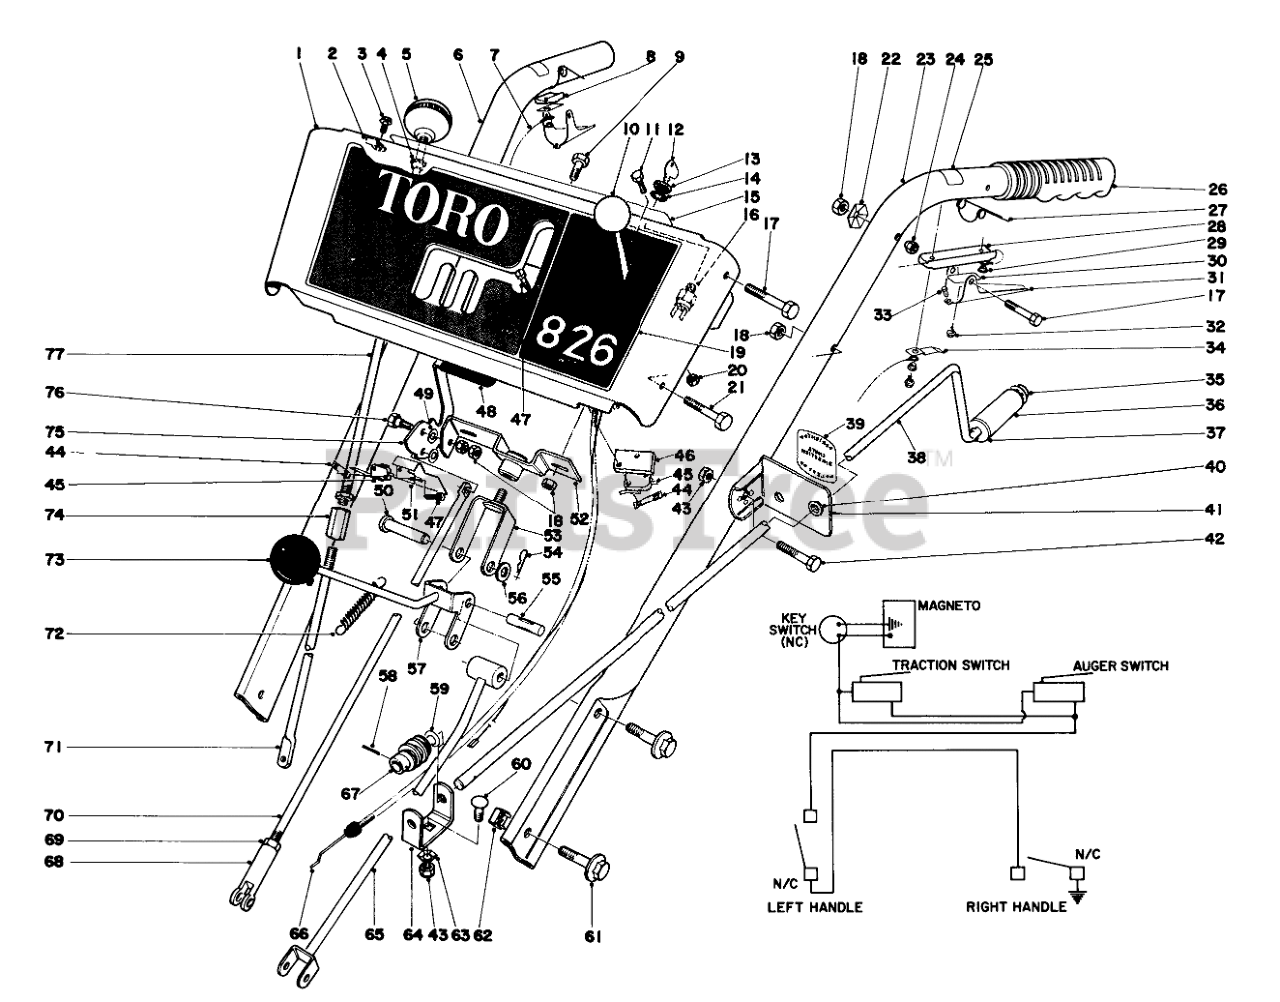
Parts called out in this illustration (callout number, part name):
1	Escutcheon Plate (Incl. Ref. #15 & 19) (Model 31763)
2	PLASTIC CLIP
3	SCREW-HWHTF
4	Nyliner Bushing
5	KNOB-LEVER
6	Handle Right
7	Wire Harness
8	Insulator
9	SCREW-HH
10	KNOB-CONTROL
11	HEX HEAD SEMS 10-24X1/2
12	Ket (set of 2)
13	NUT-HH
14	WASHER-TOOTH, INTERNAL
15	Decal Escutcheon Back
16	Switch
17	SCREW-HH
18	NUT-LOCK, CONE
19	Decal Escutcheon (Model 31763)
20	Nut
21	SCREW-HH
22	Washer
23	Handle L.H.
24	NUT-CAP
25	Decal Safety Interlock
26	Grip Handle
27	INTERLOCK SPRING
28	Insulator
29	WASHER INSULATOR
30	INTERLOCK CONTACT
31	Safety Lever
32	Screw
33	1/4 PLASTIC RIVET
34	CONTACT BRACKET
35	RETAINER-PUSH ON
36	CHUTE CONTROL GRIP
37	WASHER-FLAT
38	ROD CHUTE CONTROL
39	Decal Chute Direction
40	Bushing
41	Bracket Chute Control Mounting (Incl. Ref. #39 & 40)
42	SCREW-HH
43	NUT-LOCK, CONE
44	NUT-SPEED
45	MICRO SWITCH
46	SWITCH MTG PAD
47	SCREW-SPH
48	AUGER CLUTCH HND GRIP
49	WASHER-PLAIN
50	PIN-CLEVIS
51	SWITCH BRKT
52	SWIVEL BLOCK WA
53	Pivot Bracket
54	PIN-HAIR
55	3/8 X 1-1/4 ROL
56	WASHER-FLAT
57	Rod Shift
58	PIN-SPRING
59	WASHER-SPRING
60	SCREW-CARR
61	SCREW-HHF
62	Retained Nut
63	WASHER-LOCK
64	WORM BRACKET
65	Trunnion
66	Throttle Contrl
67	GEAR-WORM, CHUTE
68	Clevis
69	NUT-HJ
70	DRAG LINK
71	LOWER WHL CLUTCH ROD
72	CONT ROD SPRING 0
74	WHL ROD COUPLING
75	Auger Clutch Handle
76	SCREW-SHOULDER
77	Rod Wheel Clutch
